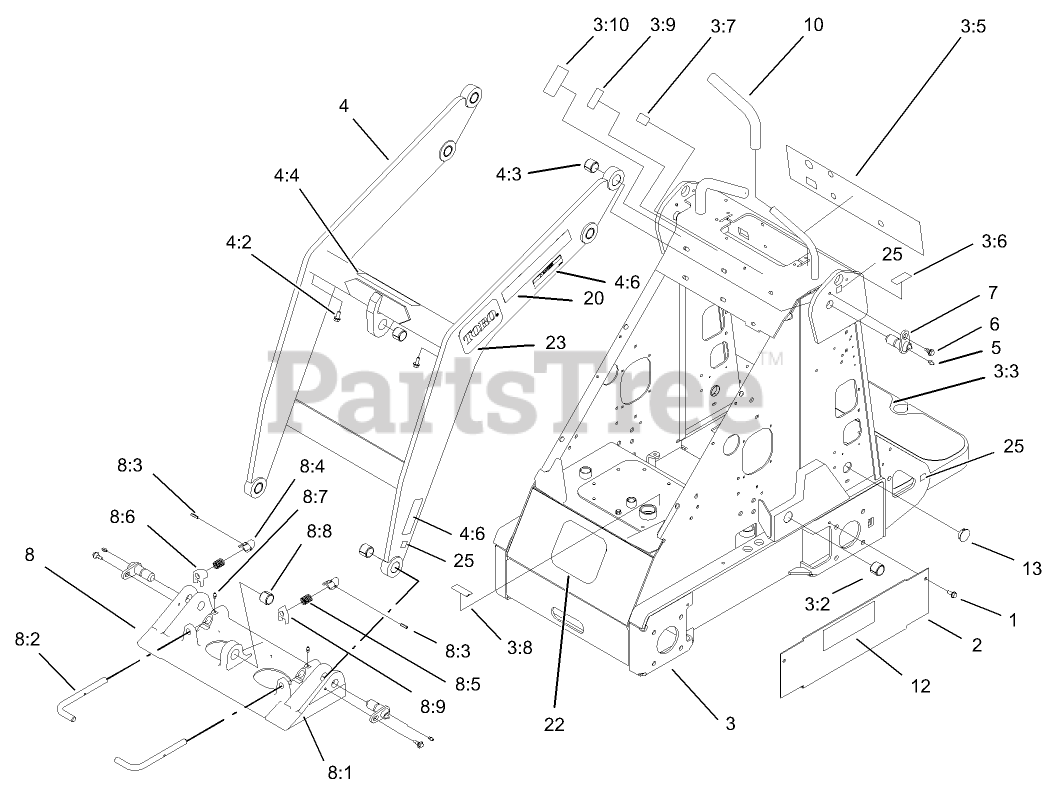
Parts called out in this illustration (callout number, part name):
1	SCREW-HWHTF
2	COVER-HOSE
3	FRAME ASM
3:2	BUSHING-TENSION
3:3	TREAD-FOOT
3:5	DECAL-PANEL, CONTROL
3:6	DECAL-THROTTLE
3:7	DECAL-LIMITER, SPEED
3:8	DECAL-OIL, HYD
3:9	DECAL-SELECTOR
3:10	DECAL-POWER, AUXILIARY
4	LOADER ASM
4:2	SCREW-HWHTF
4:3	BUSHING-TENSION
4:4	DECAL-CAUTION
4:6	DECAL-PINCH
5	FITTING-GREASE
6	BOLT-SHOULDER
7	PIN-PIVOT
8	QUICK ATTACH ASM
8:1	MOUNT-ATTACH, QUICK
8:2	PIN-LOCKING
8:3	PIN-GROOVED
8:5	SPRING-COMPRESSION
8:6	STOP-RH
8:7	FITTING-GREASE
8:8	BUSHING-TENSION
8:9	STOP-LH
10	GRIP-CUSHION
13	PLUG-HOLE
20	DECAL
22	DECAL
23	DECAL
25	DECAL-POINT, LIFT
